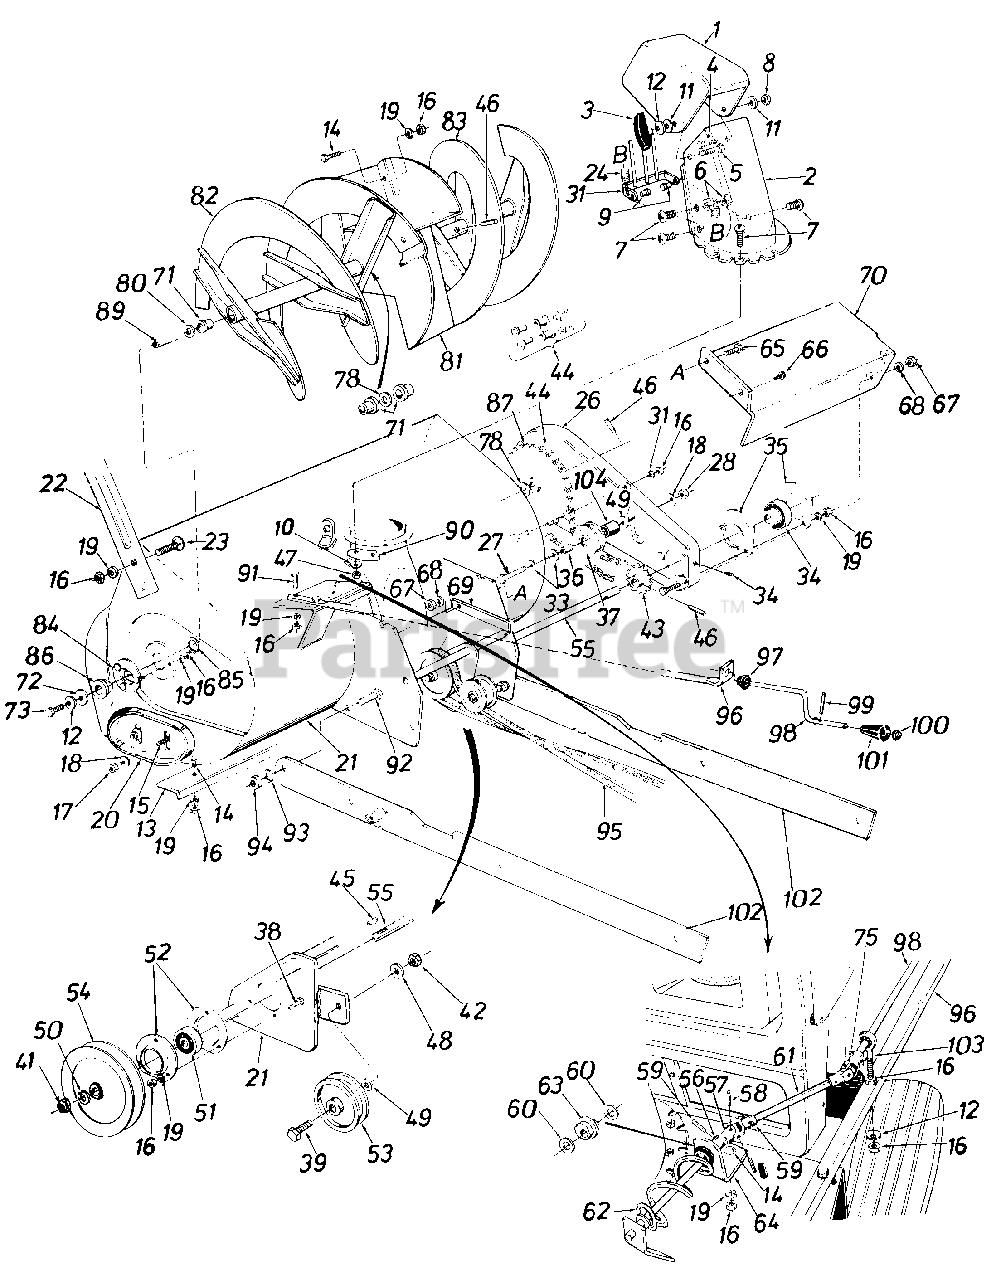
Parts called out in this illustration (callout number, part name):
1	Upper Chute
2	Lower Chute
3	Knob Handle Ass'y.
4	Truss Mach. Scr. 5/16-18 x .75" Lg.
5	Carriage Bolt 5/16-18 x 1.0"*
6	Hex Cent. L-Nut 5/16-18 Thd.
7	Truss Mach. Scr. 1/4-20 x .75" Lg.
8	Hex Cent. L-Nut 5/16-18 Thd.
9	Shld. Nut 1/4-20 Thd.
10	Fl. Wash. 1/4" I.D.
11	Fl.Wash. .344" I.D. x 1.125"
12	Bell. Wash. .345" I.D. x .88"
14	Carriage Bolt 5/16-18 x .62"
15	Carriage Bolt 3/8-16 x .62"*
16	Hex Nut 5/16-18 Thd.*
17	Hex Jam Nut 3/8-16 Thd.
18	Bell. Wash. .40 I.D. x .88"
19	L.Wash. 5/16" I.D.*
20	Slide Shoe
21	Spiral Hsg. Ass'y.36"
22	Guide 81ade
23	Carriage Bolt 5/16-18 x .62"*
24	Extension Spring
26	Chain Guard Ass'y.
27	Hex Bolt 3/8-16 x 2.00 4.*
28	Hex Inst.Nut 3/8-16 Thd.
33	Fl.Wash. .385" I.D. x .87" O.D.
34	Ball Brg. .75" I.D.
35	Flangete
36	Spacer .375" I.D. x .60" O.D.
37	Fl.ldler w/Flanges 1.875
38	Hex Sems Boit 5/18x .75" Lg.
39	Hex Bolt 3/8-16 x 1.75" 4.*
41	Hex Jam Nut 3/4-10 Thd.
42	Hex Jam Nut 3/8-16 Thd.
43	Sprocket Ass'y.14 Teeth
44	#420 Chain x 1/2" Pitch- 77 Links
45	#61 Hi-Pro-Key 3/16 x 5/8"
46	Spring Pin Spir. 5/16" Dia. x 1.75" Lg.
47	Hex L-Nut 1/4-20 Thd.
48	L.Wash. 3/8" I.D.*
49	Fl.Wash. .406" I.D. x 1.25"
50	Spring L.Wash. 3/4" I.D.
51	Self-Aligning Brg.
52	Flangete
53	Idler Pulley
54	5/8V Pulley .75" I.D. x 6"
55	Drive Shaft Ass'y
56	Joint Brkt. Ass'y.
57	Joint Block
58	Oval Head Rivet
59	Spiral Pin 1/8" Dia.
60	Fl.Wash. .385" I.D. x .62"
61	Chute Crank Ext. Rod
62	Chute Crank Ass'y. R.H.
63	Plastic Bushing .380" I.D.
64	Chute Crank Brkt.
65	Hex Bolt 1/4-20 x .62" Lg.*
66	Hex Wash. S-Tap Scr. 1/4-20 x .50" Lg.
67	Hex Nut 1/4-20 Thd.*
68	L.Wash. 1/4" I.D.4
69	Belt Cover
70	Drive Shaft Cover
71	Plastic Bushing
72	Washer .39" I.D. x 1.75" O.D
73	Hex Bolt 5/16-18 x .88" Spec
75	Coter Pin 3/32" Dia.
78	Fl.Wash. 1.03" I.D. x 1.62"
80	Fl.Wash. 1.0" x 1.75"
85	Snap Ring for 1.50" Shaft
86	Flange Brg. w/flats 1.00" I.D.
87	Sprocket Hub Ass.y. 40 Teet
89	Spiral Axle
90	Chute Flange Keeper
91	Hex Bolt 5/16-18 x 1.5" 4.*
92	Hex Bolt 1/2-13 x 1.25" Lg.*
93	L.Wash. 1/2" I.D.*
94	Hex Nut 1/2"13 Thd.*
95	"V" Belt
98	Chute Crank 34.5" L.g
99	Roll Pin .12 Dia. x .63
100	Push Nut 3/8" Rod
101	Knob Black
102	Linkage Arm
103	Eye Bolt 5/16-18 x 3.0" Lg.
104	Idler Spacer
